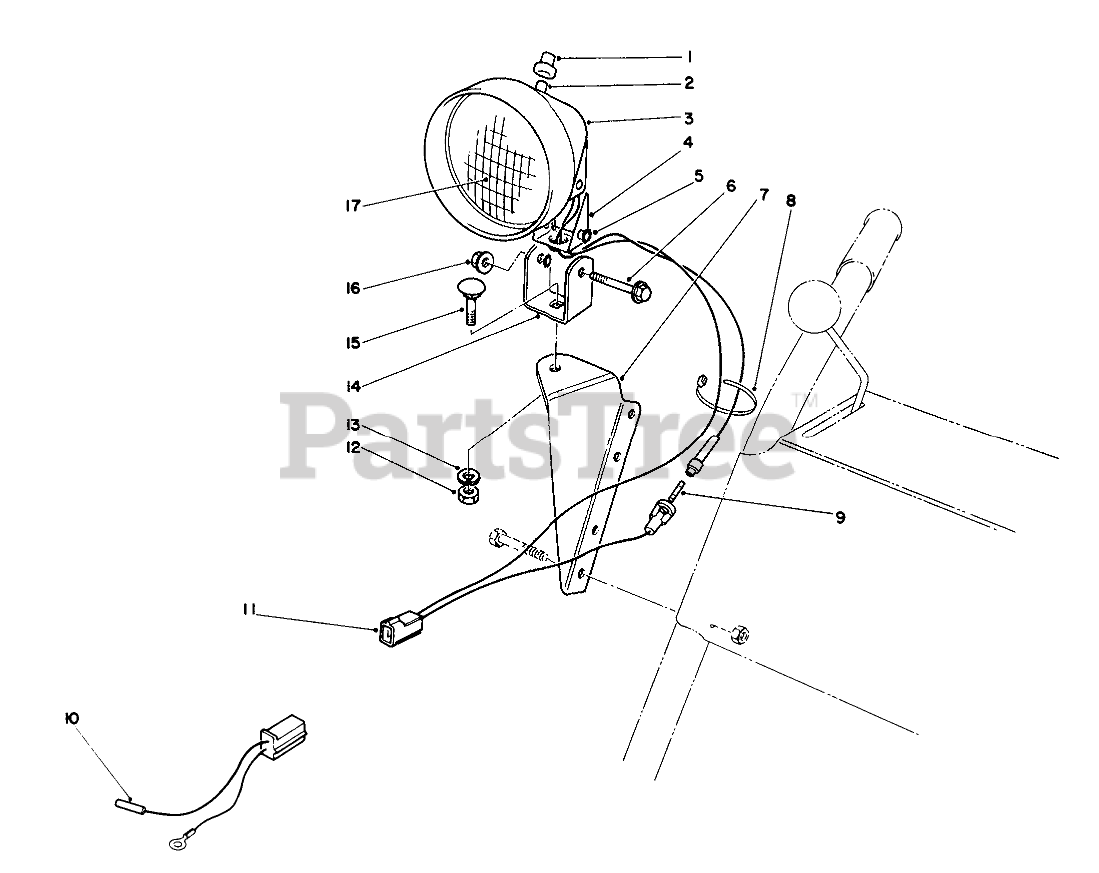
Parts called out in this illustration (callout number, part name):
1	BOOT-SWITCH
2	SWITCH ASM
3	Bucket-Headlamp
4	TO BE DISCONTINED-NOT NEEDED ON PRODUCT
5	WASHER-LOCK
6	SCREW-HH
7	LAMP MOUNT B
8	TIE-CABLE
9	Fuse-71/2 Amp
10	WIRE ASM
11	WIRE ASM
12	NUT-HEX
13	WASHER-LOCK
14	BRACKET
15	BOLT-CARR
16	NUT-HF
17	SEALED BEAM
